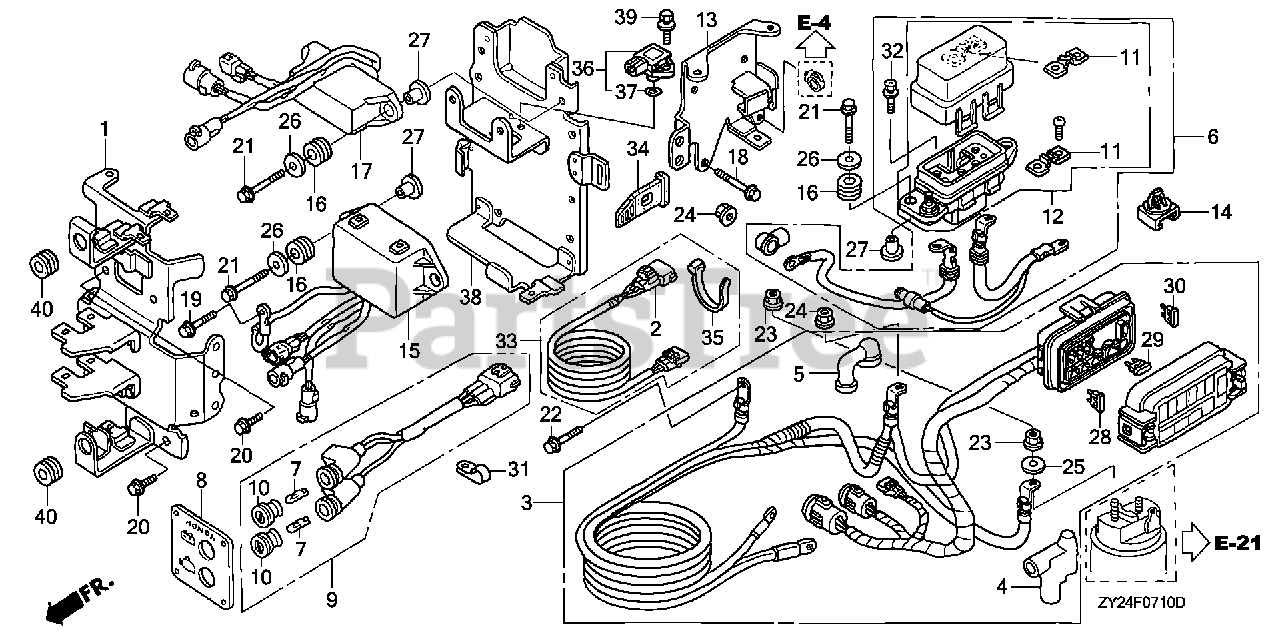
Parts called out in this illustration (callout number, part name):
1	BRACKET, CONNECTOR A
2	WIRE ASSY., INDICATOR (3P/3P) (ANALOG)
2	WIRE ASSY., INDICATOR (3P/6P) (ANALOG)
2	WIRE ASSY., INDICATOR (DIGITAL)
3	CABLE ASSY., STARTER
4	COVER, STARTER TERMINAL
5	COVER, MAGNETIC SWITCH TERMINAL
6	CABLE ASSY., ALTERNATOR FUSE
7	BULB, WEDGE BASE (T6.5) (12V 3W)
8	PANEL, INDICATOR (2-BULB)
9	LAMP ASSY., INDICATION (2-BULB)
10	LENS, SPEEDOMETER PILOT
11	FUSE (150A)
12	BOX ASSY., FUSE (150A)
13	BRACKET, FUSE BOX
14	CLIP, CONNECTOR HOLDER (B)
15	RELAY ASSY., POWER TILT
16	GROMMET, RELAY
17	RELAY ASSY., MAIN
18	BOLT, FLANGE (6X14) (CT200)
19	BOLT, FLANGE (6X12)
20	BOLT, FLANGE (6X10)
21	BOLT, FLANGE (6X22)
22	BOLT, FLANGE (8X18)
23	NUT-WASHER (8MM)
24	NUT-WASHER (6MM)
25	WASHER, PLAIN (8MM)
26	WASHER, PLAIN (6MM)
27	COLLAR, MODULE IGNITION CONTROL CASE (CDI)
28	FUSE, MINI (10A)
29	FUSE, MINI (15A)
30	FUSE, MINI (30A)
31	CLAMP F, CABLE
32	BOLT-WASHER (6X16)
33	CORD KIT, INDICATOR (3P/6P) (ANALOG)
36	SENSOR ASSY., MAP
39	BOLT-WASHER (5X18)
